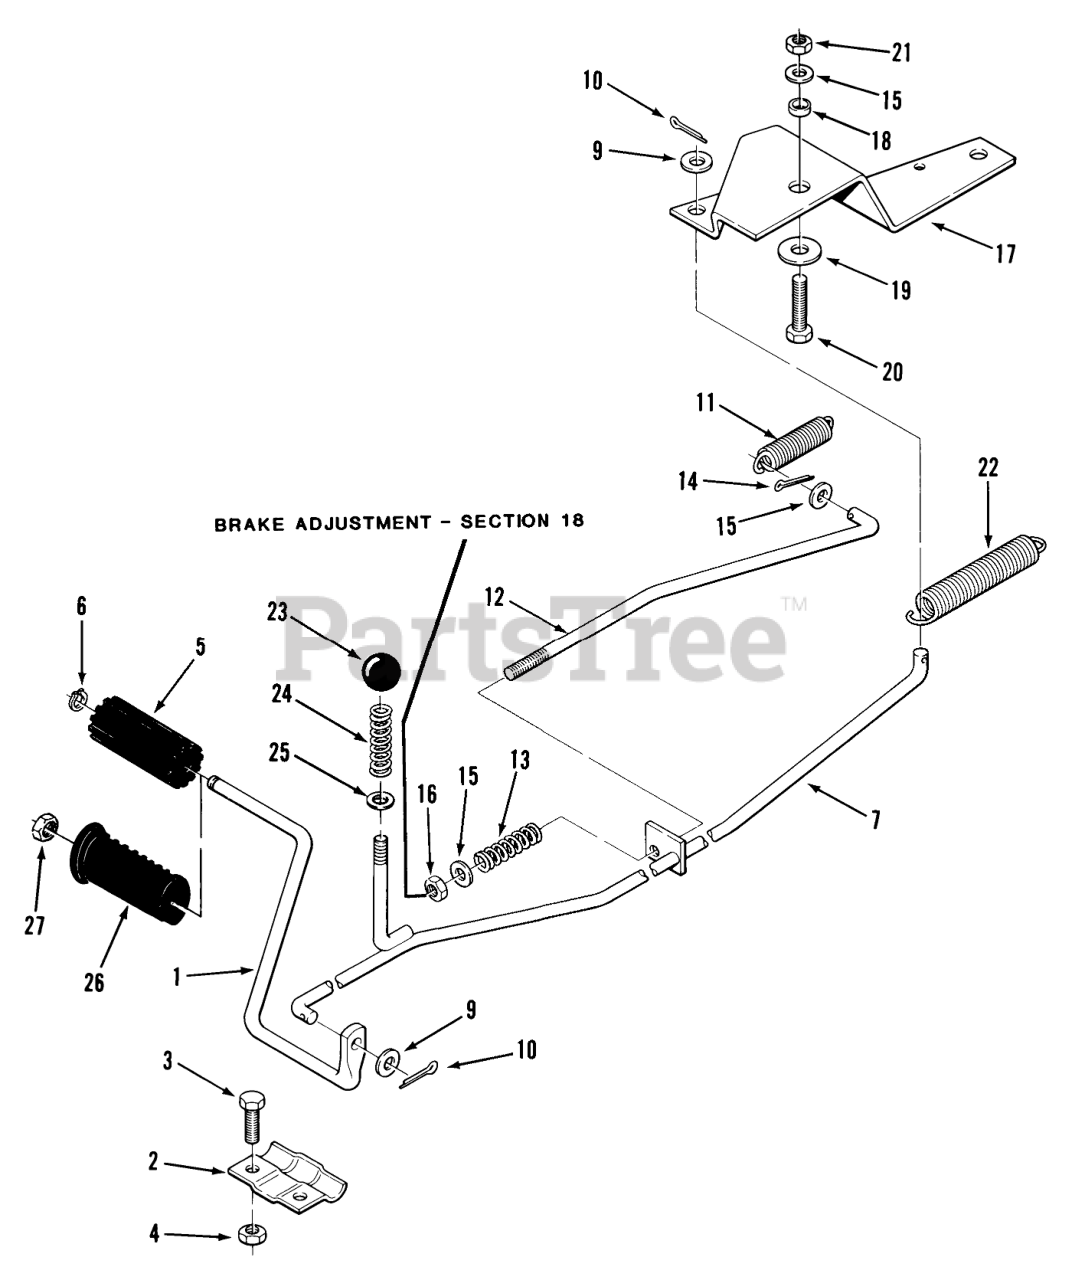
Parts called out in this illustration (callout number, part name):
1	ROD-BRAKE PEDAL R
2	SPINDAL SUPPORT R
3	Bolt
4	NUT
5	PAD-CLUTCH/BRKE PDL
6	Grip Ring
7	ASSY CLUTCH ROD
9	Washer
10	Cotter Pin
11	SPRING-EXTENSION
12	ROD BRAKE
13	SPRING-COMPRESSION
14	Cotter Pin
15	Washer
16	NUT
17	LEVER CLUTCH R
18	SPACER
19	WASHER
20	Bolt
21	NUT
22	SPRING EXTENSION
23	KNOB
24	SPRING
25	WASHER
26	Clutch/Brake Pedal 112-C Only
27	Jam Nut
